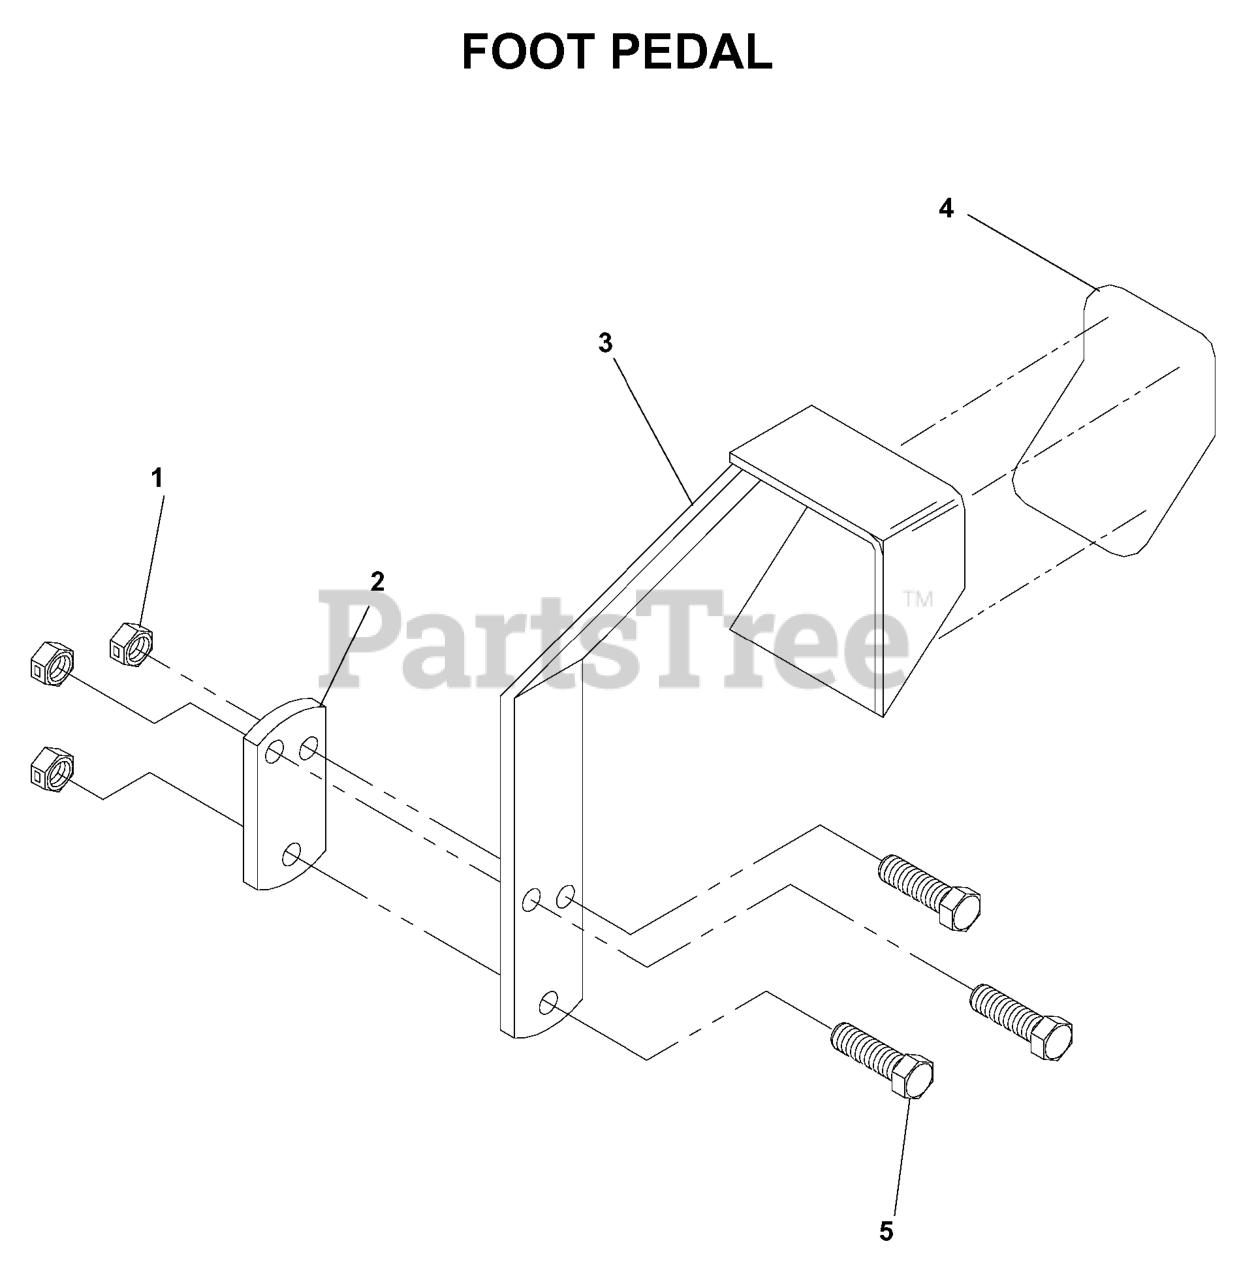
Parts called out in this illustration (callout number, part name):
1	NUT 3/8-16 NYLOC
2	TIGHTENING PLATE BLK
3	LIFT PEDAL BLK
4	ANTI-SKID PAD
5	HCS 3/8C X 1 1/2
